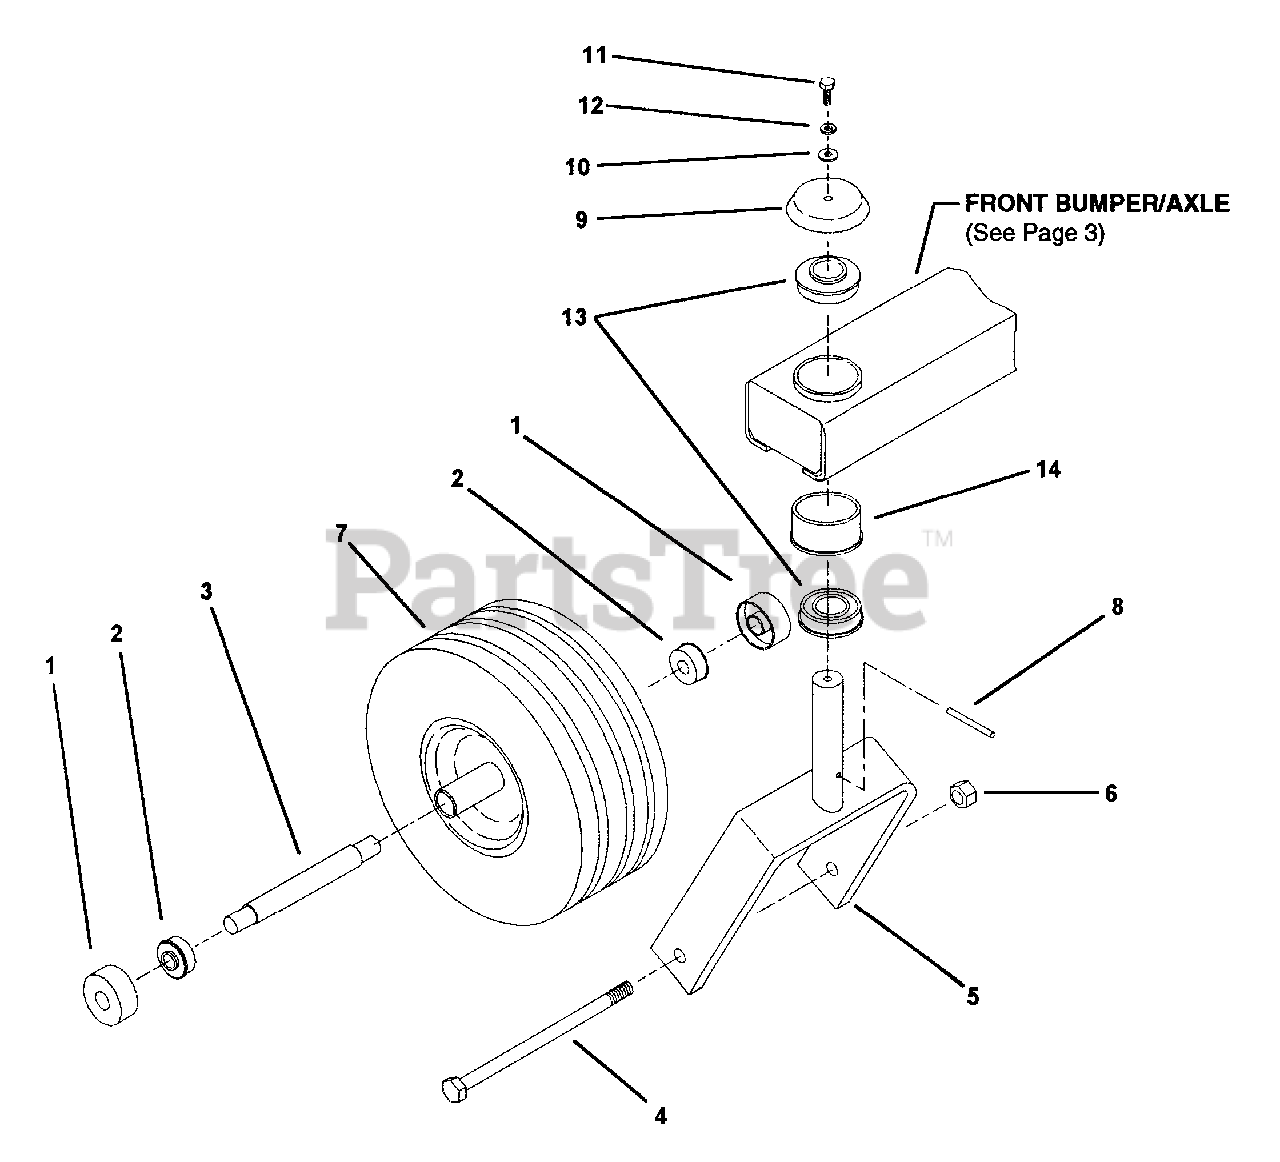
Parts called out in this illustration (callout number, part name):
1	SHIELD, BEARING
2	BEARING, 5/8 I.D. X 1-3/8 O.D.
3	SPACER, BEARING
4	BOLT, 1/2-13 X 8" GR.5
5	CASTER WELDMENT, UNI JOYSTICK
6	NUT, 1/2-13, STOVER
7	TIRE, 13X5-6, ON WHEEL, (RIBBED TREAD)
8	PIN, SPIRAL, 3/16 X 2 HEAVY DUTY
9	CAP, BEARING
10	WASHER, FLAT STD. 1/4"
11	BOLT, 1/4-20 X 5/8" GR.5
12	LOCK WASHER, 1/4" HEAVY SPRING
13	BEARING, SPD SF-16-32 W/O COLLAR
14	SPACER, CASTER BEARING
